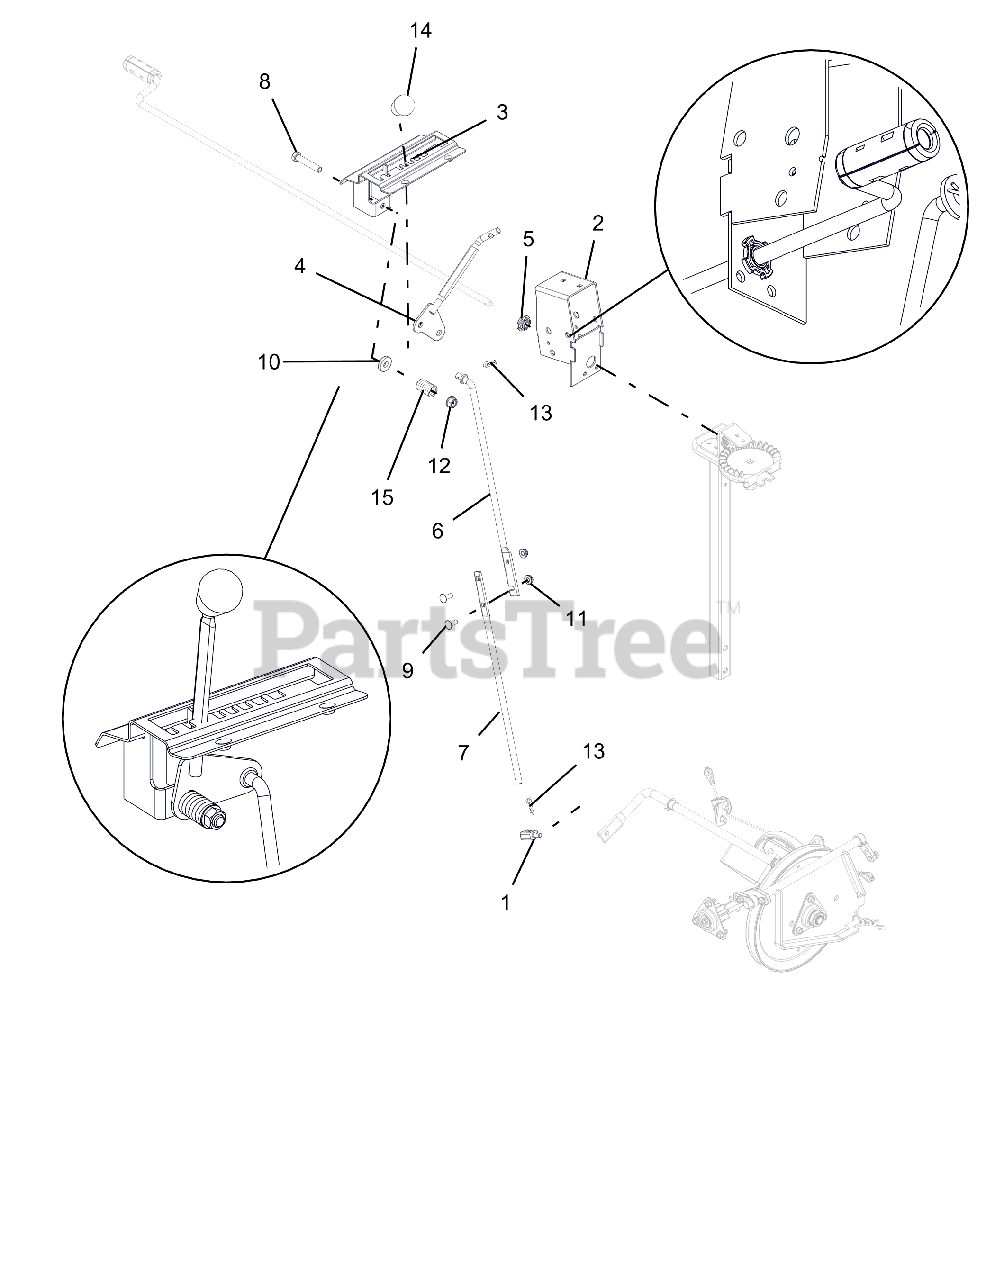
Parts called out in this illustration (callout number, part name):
1	PIVOT,SHIFT ROD .375-16(TRUNN)
2	WELDMENT, BRACKET INTERLOCK
3	WELDMENT, DETENT PLATE-COMPACT
4	LEVER, CONTROL-SHIFT(WELDMENT)
5	CRANK BUSHING, NYLON CHUTE BK
6	ROD, SHIFT - UPPER
7	ROD, SHIFT - LOWER
8	@BLT-HEX .38-16X2.00 GR5 YWZC
9	@BLT-RDHDSQNK .25-20X.75 G5YZ
10	WSHR-FL-STL .406X1.00X.188 YWZ
11	@NUT-LK-CTR-FLG .25-20 YWZC
12	@NUT-LK-TOP-FLG .38-16 YWZC
13	PIN-HAIR INT .08X.18X1.18 YWZC
14	KNOB,SOFT TEARDROP,PUSH-ON BLK
15	SG-COMP .125X.781X1.250
